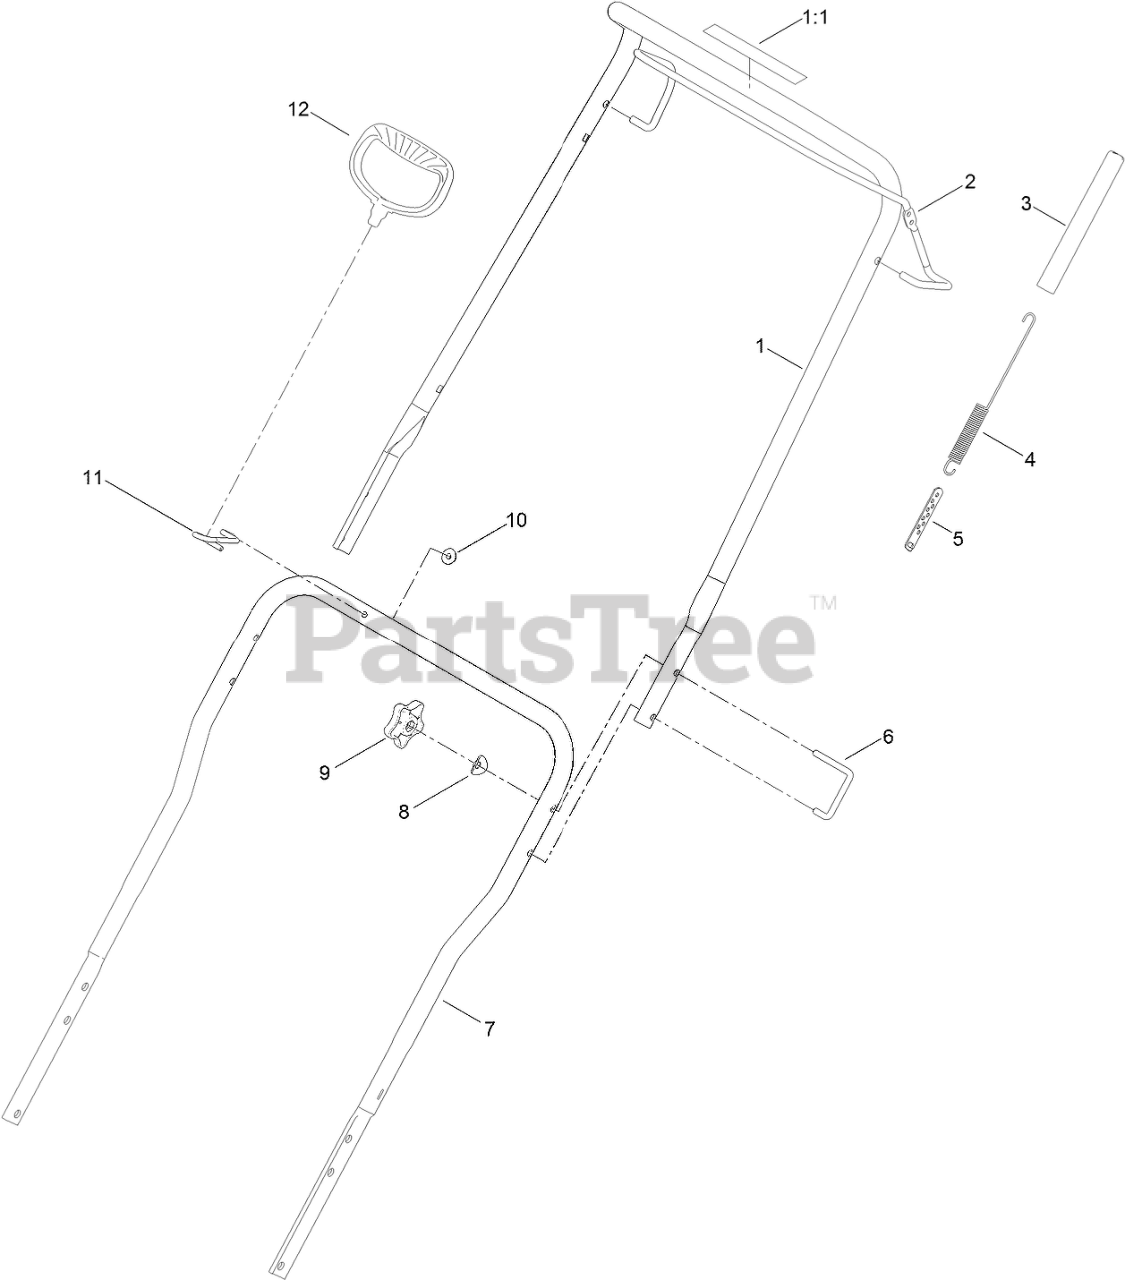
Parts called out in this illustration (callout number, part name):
1	UPPER HANDLE ASM
1:1	DECAL-DRIVE, ROTOR
2	BAIL-CONTROL
3	COVER-SPRING
4	SPRING-EXTENSION, CLUTCH
5	ADJUSTER-CABLE, CLUTCH
6	LOCK-HANDLE
7	HANDLE-LOWER
8	WASHER
9	KNOB-HANDLE
10	NUT-HEX FLG
11	GUIDE-ROPE
12	HANDLE-RECOIL
